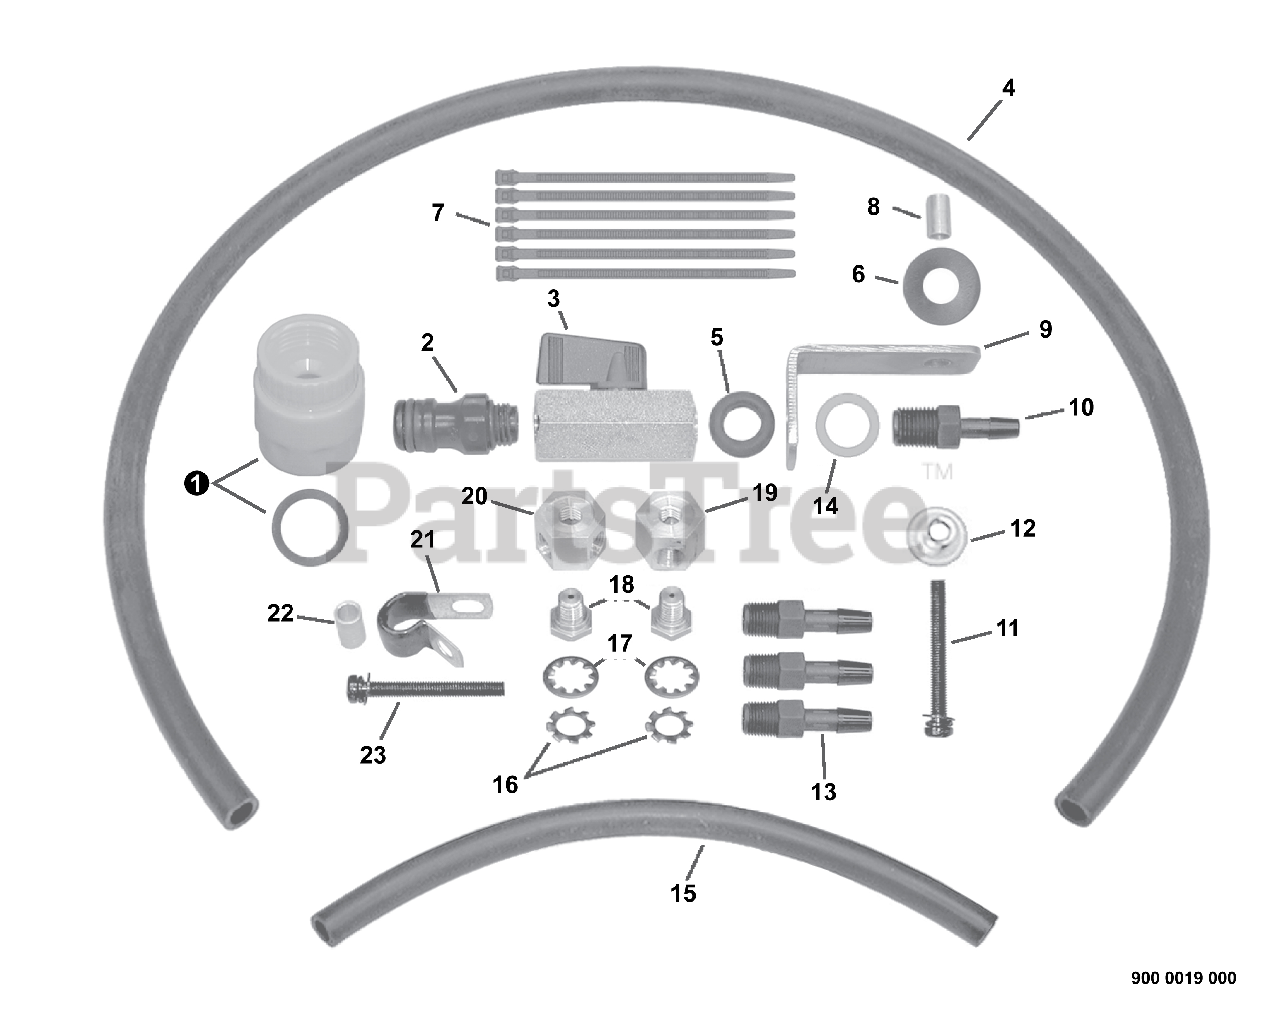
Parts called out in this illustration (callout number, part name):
1	FITTING W/GASKET, FEMALE -- QUICK-CONNECT
2	FITTING, MALE -- QUICK-CONNECT
5	GROMMET
6	WASHER - RUBBER
7	TIE, CABLE - SMALL
9	BRACKET, VALVE
10	FITTING
11	SCREW - 5X40
13	FITTING
14	WASHER - 14 -- NYLON
16	LOCKWASHER
17	LOCKWASHER
19	ADAPTER - 1 HOLE
20	ADAPTER - 2 HOLE
23	SCREW - 5X55
